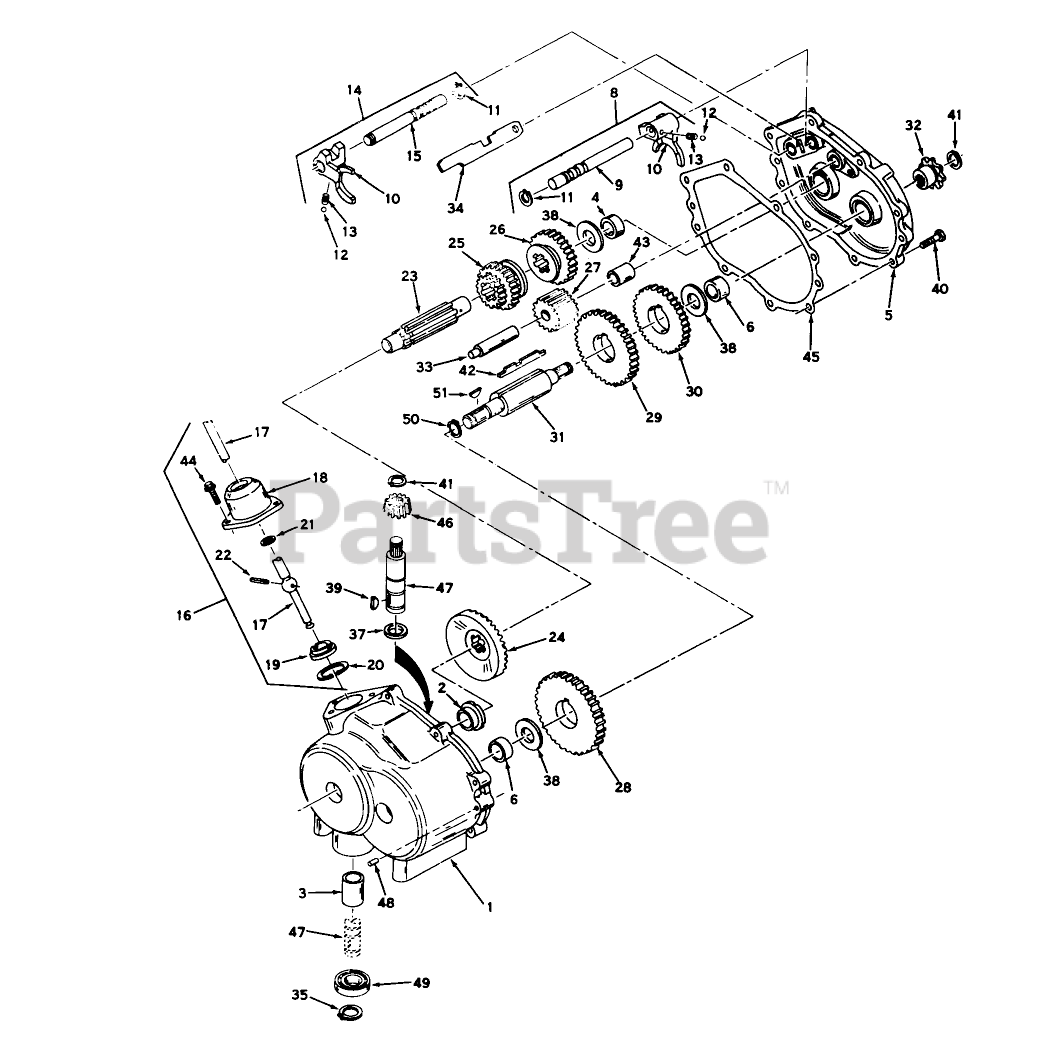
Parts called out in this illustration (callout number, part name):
1	Case Assy., Transmission (Incl. Nos. 2, 3 6)
2	Bearing, Bronze
3	Bearing, Bronze
4	Bearing, Bronze
5	Cover Assembly, Transmission (Incl. Nos. 4 6)
6	Bushing, Bronze
8	Shift Rod Assy (1st and Rev.)(Incl. Nos. 26 thru 30)
9	Shift Rod
10	Shift Fork
11	Ring-Snap
12	Piston ASM
13	Spring
14	Rod Assy., Shift (Incl. Nos. 10 thru 13 15)
15	Rod, Shift
16	Lever Housing Assy., Shift (Incl. Nos. 17 thru 22)
17	Lever, Shift
18	Shift Lever Housing
19	Keeper-Shift Lever
20	Ring-Snap
21	O Ring
22	Roll Pin
23	Shaft, Shifter
24	Gear, Bevel (33 teeth)
25	Gear, Shift 1st 2nd)
26	Gear, Shift 3rd Rev.)
27	Idler, Reverse
28	Gear (39 teeth)
29	Gear (34 teeth)
30	Gear (30 teeth)
31	Shaft, Output
32	Sprocket (8Teeth)
33	Shaft, Reverse Idler
34	Stop, Shifter
35	Ring-Snap
37	Bearing, Thrust
38	Washer
39	Key, Woodruff
40	Screw-Thread Forming
41	Ring-Retainer
42	Key, Countershaft
43	Reverse Idler Spacer
44	Screw
45	Gasket, Transmission
46	Pinion, Input
47	Shaft, Input
48	Dowel Pin
49	Bearing-Ball
50	Snap Ring
51	Kev. Woodruff
